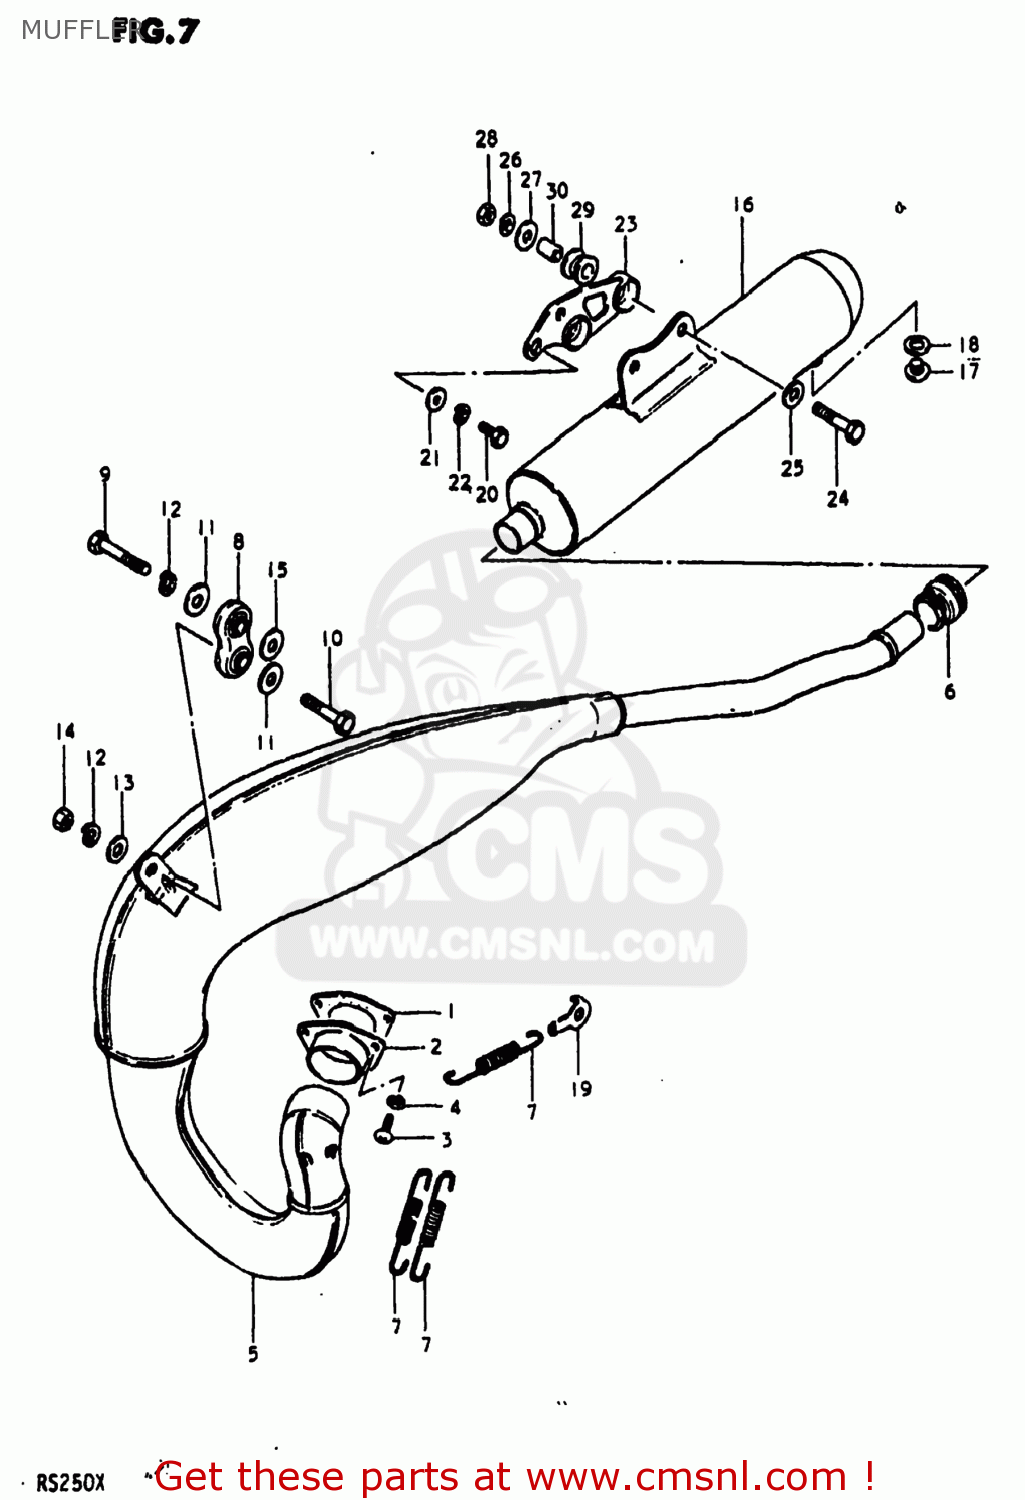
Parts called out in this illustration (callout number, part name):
1	GASKET,EXHAUST PIPE (MCA)
2	FLANGE,EXHAUST PIPE
3	SCREW
4	LOCK WASHER
5	BODY,MUFFLER
6	CONNECTOR,MUFFLER
7	SPRING
8	DAMPER,MUFFLER
9	BOLT
10	BOLT
11	WASHER
12	LOCK WASHER
13	WASHER
14	NUT
15	WASHER
16	MUFFLER ASSEMBLY
17	PLUG(12X9)
18	GASKET(12X16X2) (NAS)
19	HOOK,MUFFLER FIT SPRING
20	BOLT, UPPER
21	WASHER
22	LOCK WASHER
23	DAMPER,MUFFLER SUPPORT
24	BOLT
25	WASHER
26	LOCK WASHER
27	WASHER (8.5X29X1.6)
28	NUT
29	CUSHION
30	SPACER (8.2X12X17)
